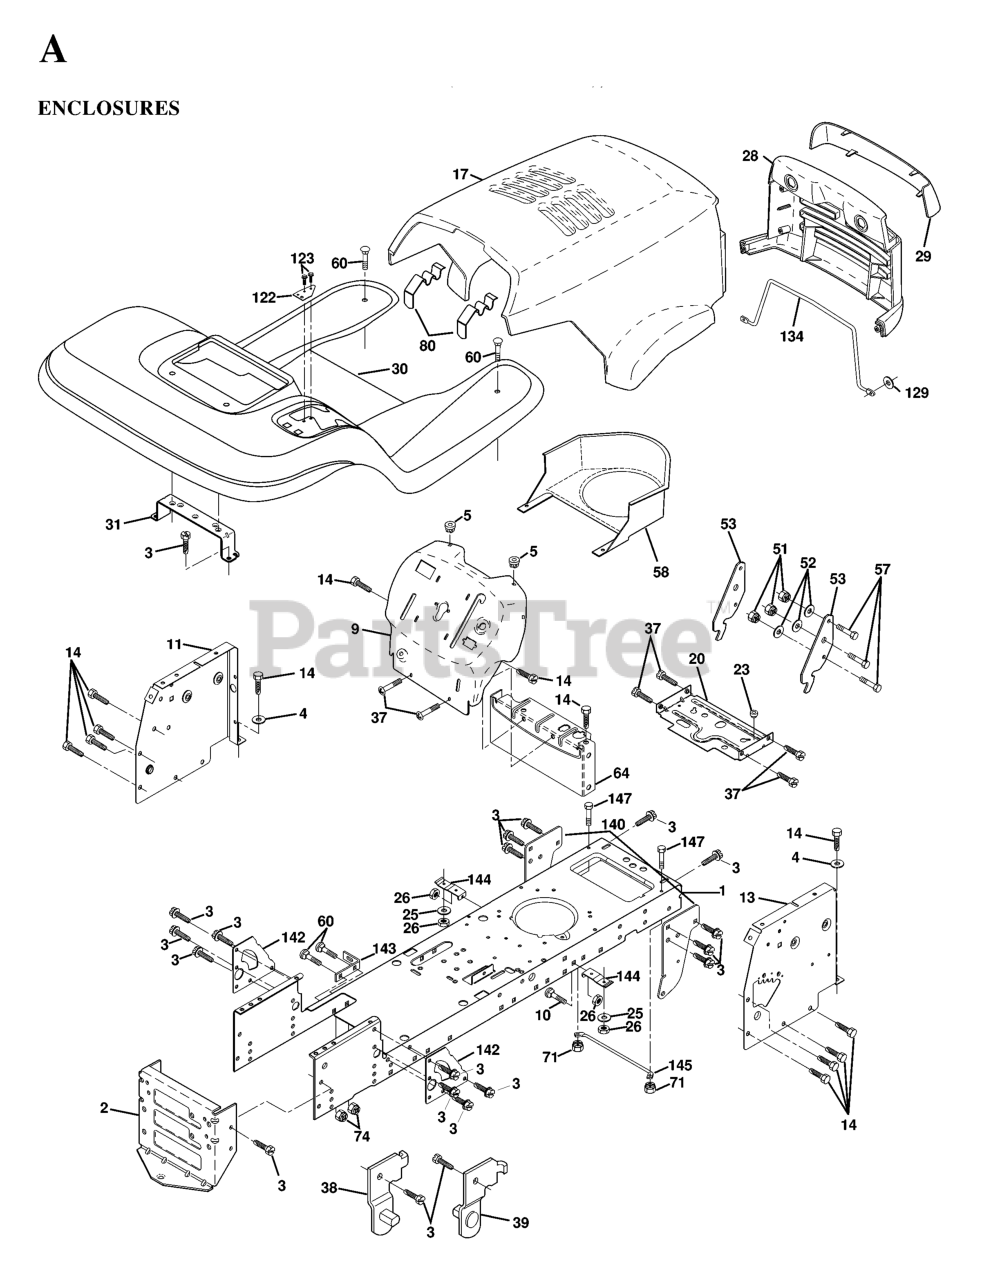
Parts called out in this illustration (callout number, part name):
1	CHASSIS WELDMENT
2	STRETCH DRAWBAR
3	SCREW
4	Washer 13/32 X 3/4 X 16 Ga.
5	BUMPER.RUBBER.HOOD
9	DASH PANEL
10	BOLT D
11	PANEL DASH LH
17	HOOD - LT/YT
20	PLATE MTG
23	BUSHING.SNAP.NYL.BLK.
25	WASHER
26	NUT
28	GRILLE LT/PL HUSQVARNA
29	LENS LT/PL HUSQVARNA
30	FENDER FOOTREST
31	BRACKET.SUPPORT.FENDER
37	Screw 5/16-18 x 1/2 Hex, Self Tapping 5/16-18 x 1/2
38	BRACKET LH PIVOT
39	BRACKET RH PIVOT
51	LOCKNUT.NYLOC.1/4-20
53	BRACKET PNT PICK OFF LT/PL
57	BOLT
58	AIR DUCT P/L/LT
60	Bolt - Rd. Hd. Sq. Neckiage 3/8 16 x 3/4
64	DASH LOWER
80	LATCH HOOD
122	BRACKET SHIFT STLT
123	SCREW.TT.#10-32X.5.3/8.FLANGE
134	ROD SUPPORT HOOD LT/PL HUSQ
140	BRACKET CHASSIS FRONT
142	PLATE REINFORCEMENT
143	BRACKET, SWAY BAR
144	BRACKET FOOTREST
